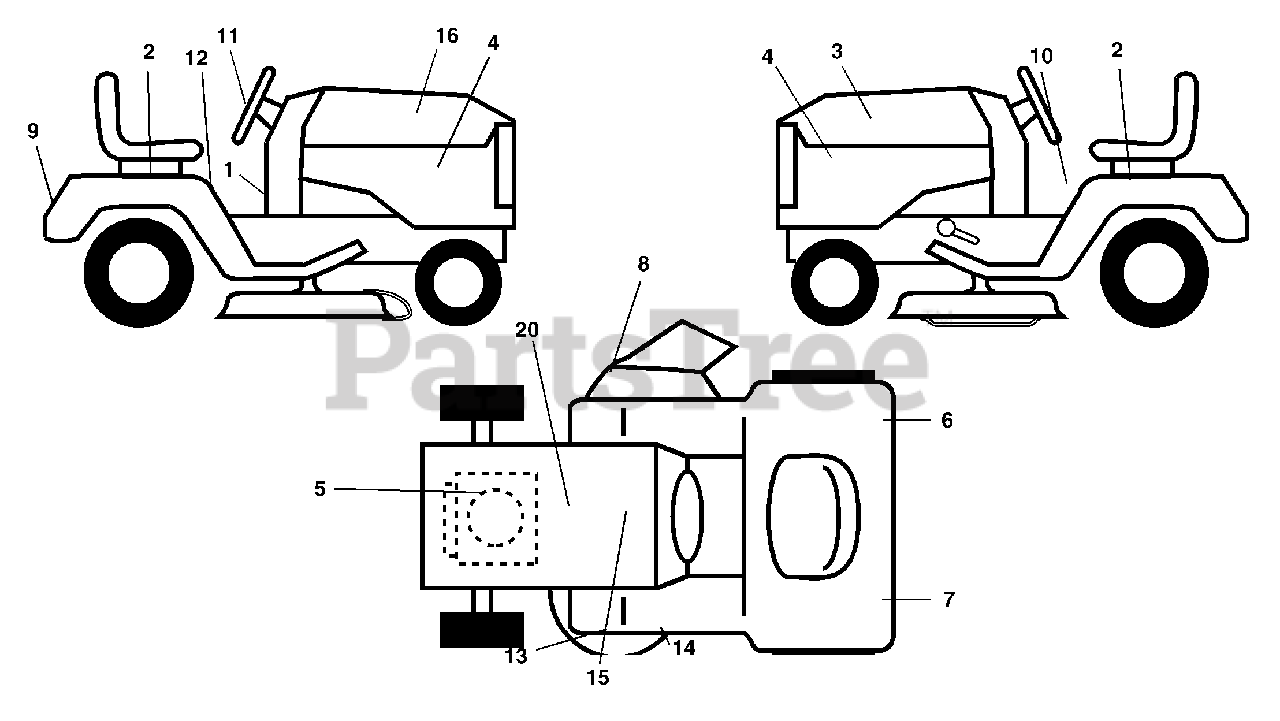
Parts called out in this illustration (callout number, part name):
1	Decal Dash
2	Decal Fender Auto
3	Decal Hood LH
4	Decal Side Panel
5	Decal HP Engine
6	Decal Reflector Rh
7	Decal Reflector Lh
8	Decal Warning Mower
9	Decal Fender Logo
10	Decal Fender Danger E/F
11	Decal Ins Strg Whl
12	Decal Fender Oper Cruise
13	Decal Deck Caution
14	Decal V-Belt Schematic
15	Decal Replace
16	Decal Hood Rh
20	Decal Bat Dan/Psn
